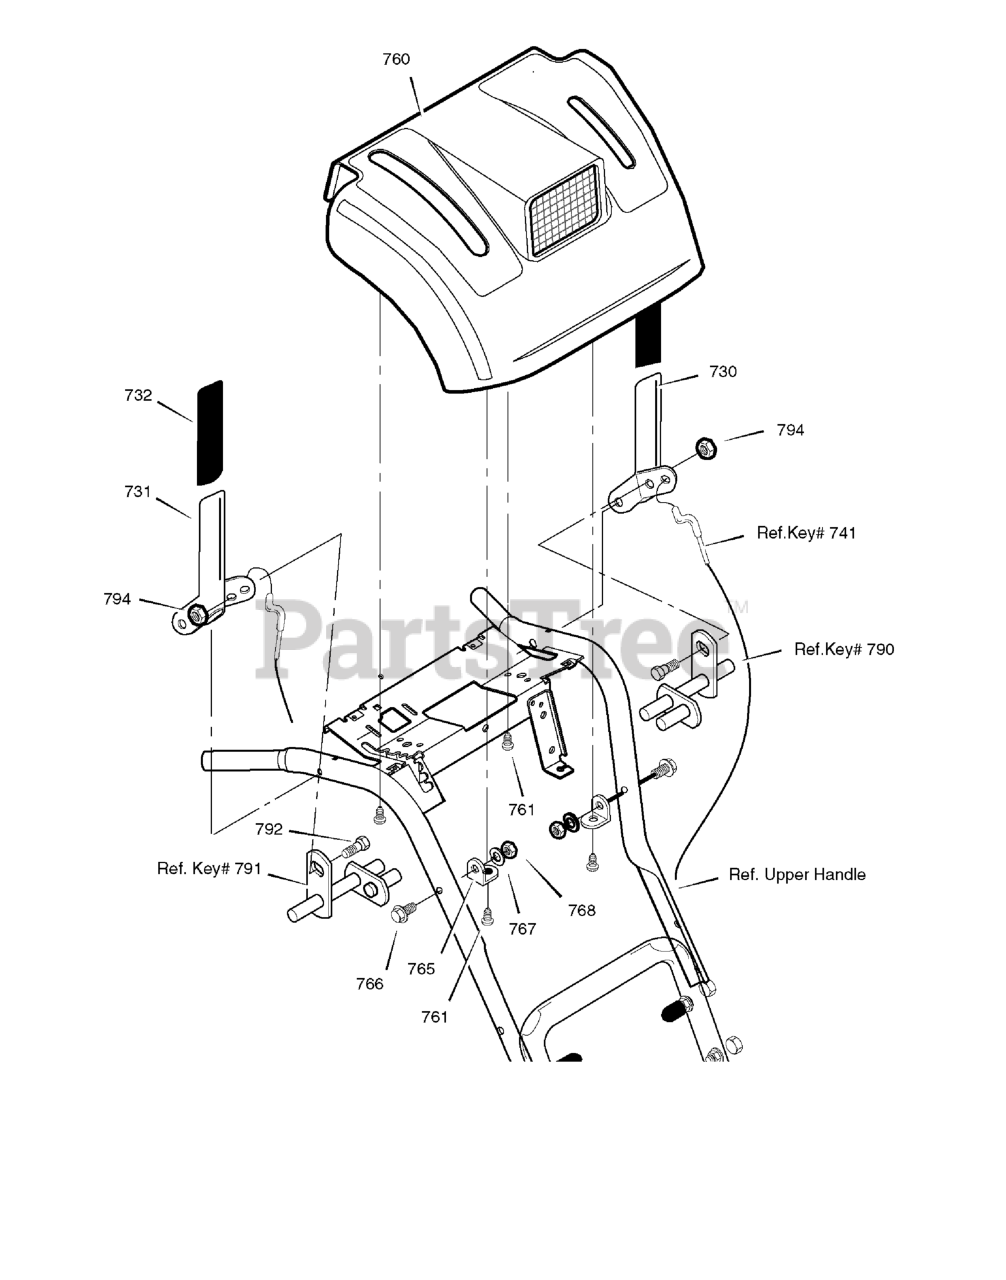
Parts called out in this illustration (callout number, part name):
730	CLUTCH HANDLE LH
731	CLUTCH HANDLE RH
732	GRIP, CLUTCH LEVER
760	PANEL, CONTROL
765	BRACKET, PANEL
766	SCREW, 5/16-18 x 1.75
767	WASHER
768	NUT, 5/16-18
792	BOLT, 1/4-20 X 0.50
794	NUT, 1/4-20
